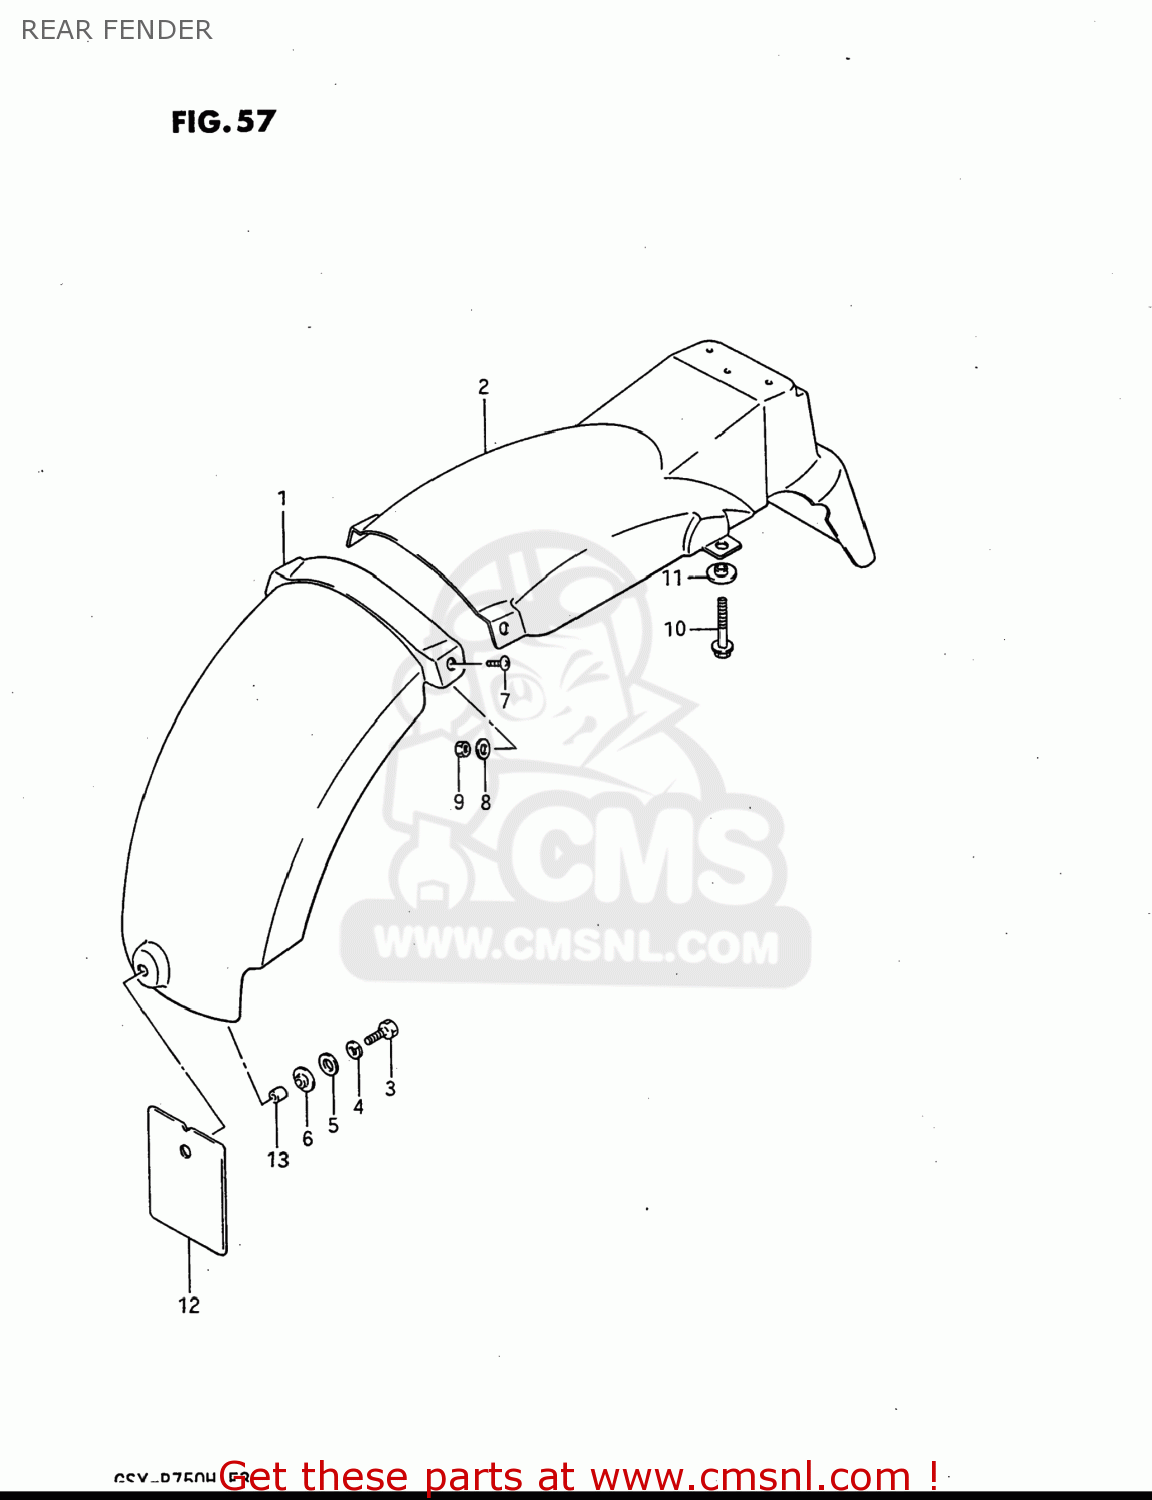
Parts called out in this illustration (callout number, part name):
1	BODY,REAR FENDER,FRONT
2	FENDER,REAR
3	BOLT 6X30
4	WASHER,LOCK
5	WASHER
6	WASHER
7	SCREW
8	WASHER
9	NUT 6MM
10	BOLT
11	WASHER
12	MUD GUARD,REAR FENDER,FRONT
13	SPACER (6.8X10X10)
